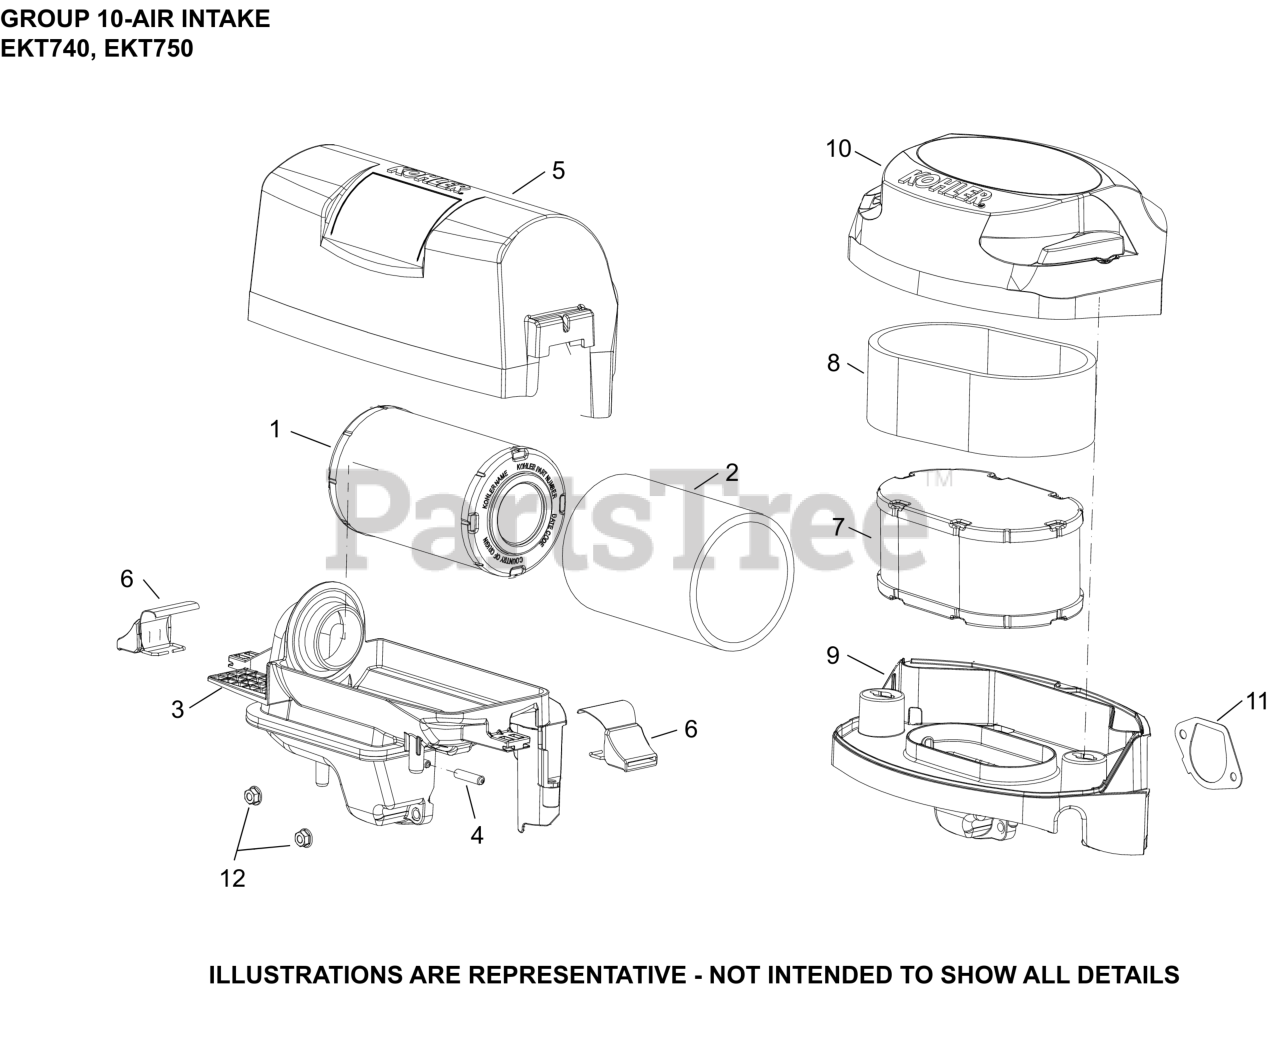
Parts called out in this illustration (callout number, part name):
4	CAP, MASKING
7	ELEMENT, AIR FILTER
8	ELEMENT, PRE-CLEANER
9	BASE ASSEMBLY, AIR CLEANER
10	COVER ASSY, AIR CLEANER
11	GASKET, AIR CLEANER BASE
12	NUT, FLG M6X1.0
